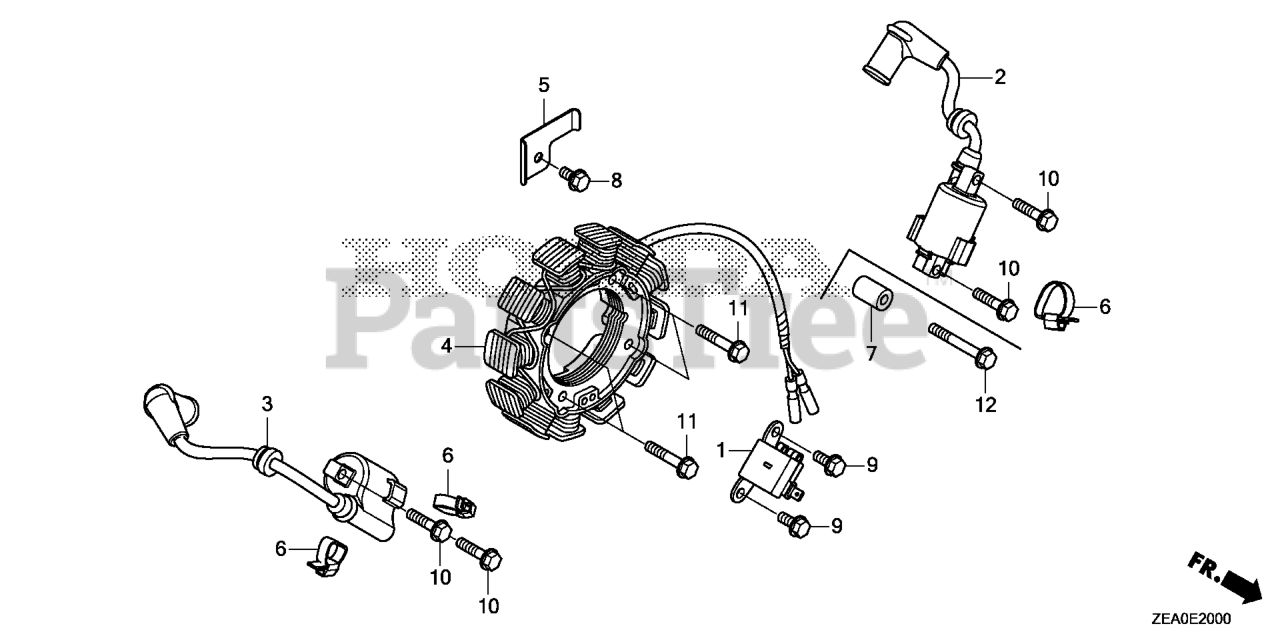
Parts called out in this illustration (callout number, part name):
1	COIL ASSY., PULSER
2	COIL, IGNITION (1)
3	COIL, IGNITION (2)
4	COIL ASSY., CHARGE (17A)
5	BRACKET, HARNESS
6	BAND, WIRE (95MM)
7	COLLAR, IGNITION COIL
8	BOLT, FLANGE (6X12) Use up to Engine SN 1543277.
9	BOLT, FLANGE (6X14)
10	BOLT, FLANGE (6X25)
11	BOLT, FLANGE (6X32)
12	BOLT, FLANGE (6X45)
